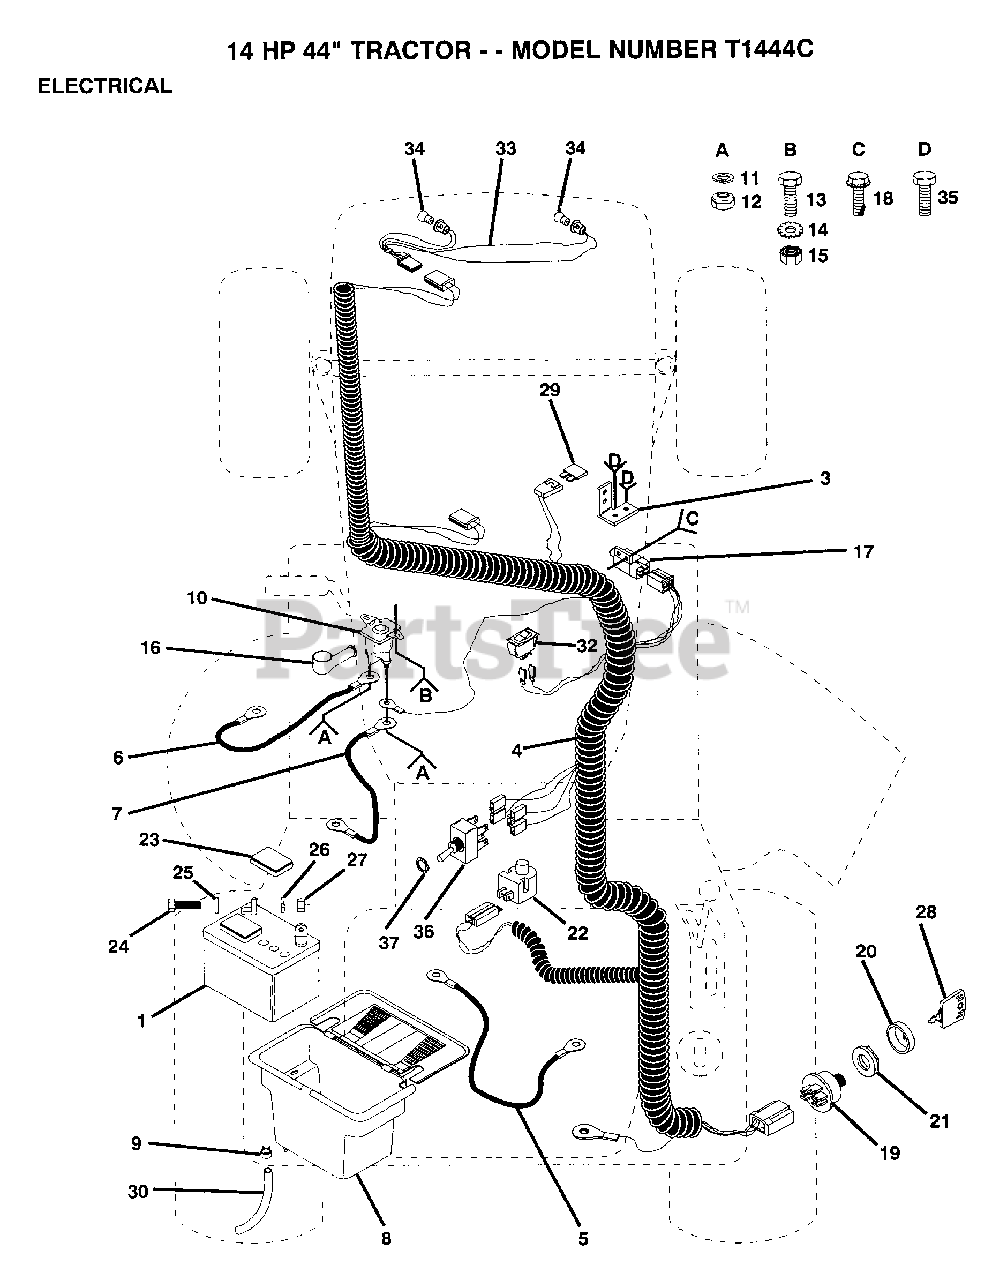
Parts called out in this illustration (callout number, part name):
3	BRACKET LT
4	"HARNESS,IGNITION"
5	CABLE T
6	"CABLE T, BATTERY"
9	HOSE CLAMP T
12	NUT
13	BOLT
15	NUT
17	SWITCH-INTER. GT
18	SCREW
21	NUT IGNITION
22	SWITCH SEAT
23	"CAP,BATTERY "
24	BOLT LT
25	WASHER
26	LOCKWASHER
29	FUSE HYT
32	SWITCH LT
33	HARNESS T
35	SCREW
36	"SWITCH,PTO"
37	HEX NUT T
